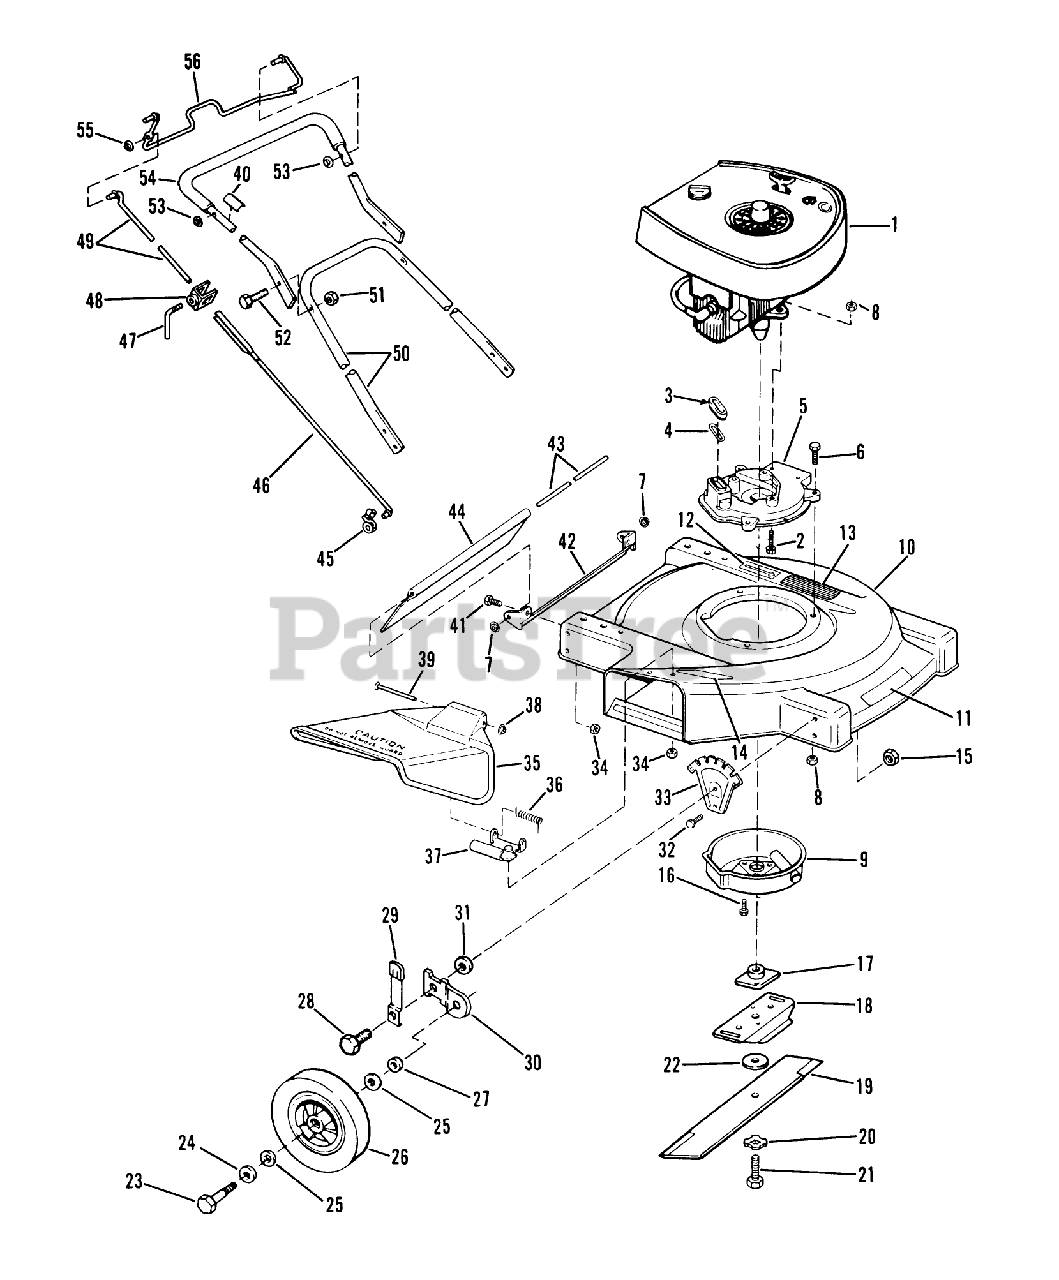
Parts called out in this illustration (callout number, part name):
3	SLEEVE
4	GASKET S
6	SCREW
8	NUT-LOCK F
13	PAD FOOT
15	LOCKNUT
16	SCREW
20	LOCKWASHER
21	BLADE BOLT
22	WASHER
23	BOLT WHEEL
24	SPACER
25	WASHER
27	WASHER WROUGHT
29	KNOB & SPRING
31	WASHER
34	LOCKNUT E
35	CHUTE DEFLECTOR AY
37	HINGE & SCREW ATA
39	PIN
42	BRACKET (12)
44	TRAILING SHIELD
45	CLIP
51	LOCKNUT E
52	SCREW - USE 137-3042
